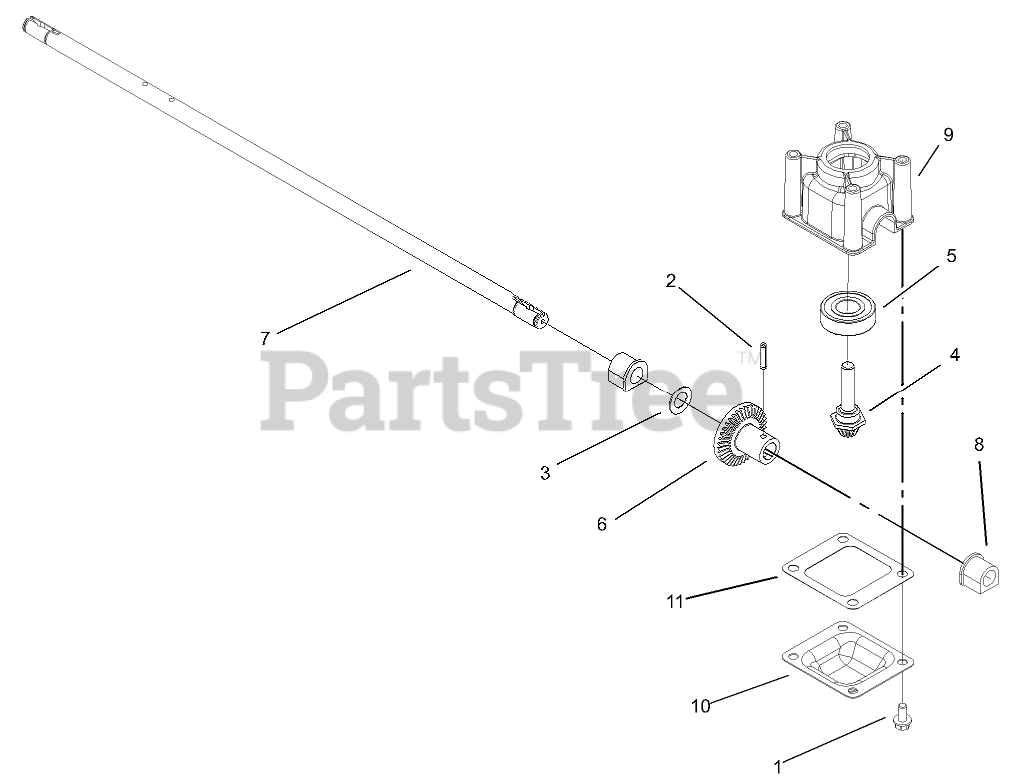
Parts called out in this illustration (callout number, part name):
1	SCREW-HWH
2	Pin-Groove
3	WASHER-PLAIN
4	PINION
5	BEARING-BALL
6	Gear-Bevel, 37t
7	Shaft-Output
8	Bushing-Shaft, Output
9	Gearcase-Upper
10	Cover-Gearcase
11	Gasket-Gearcase
